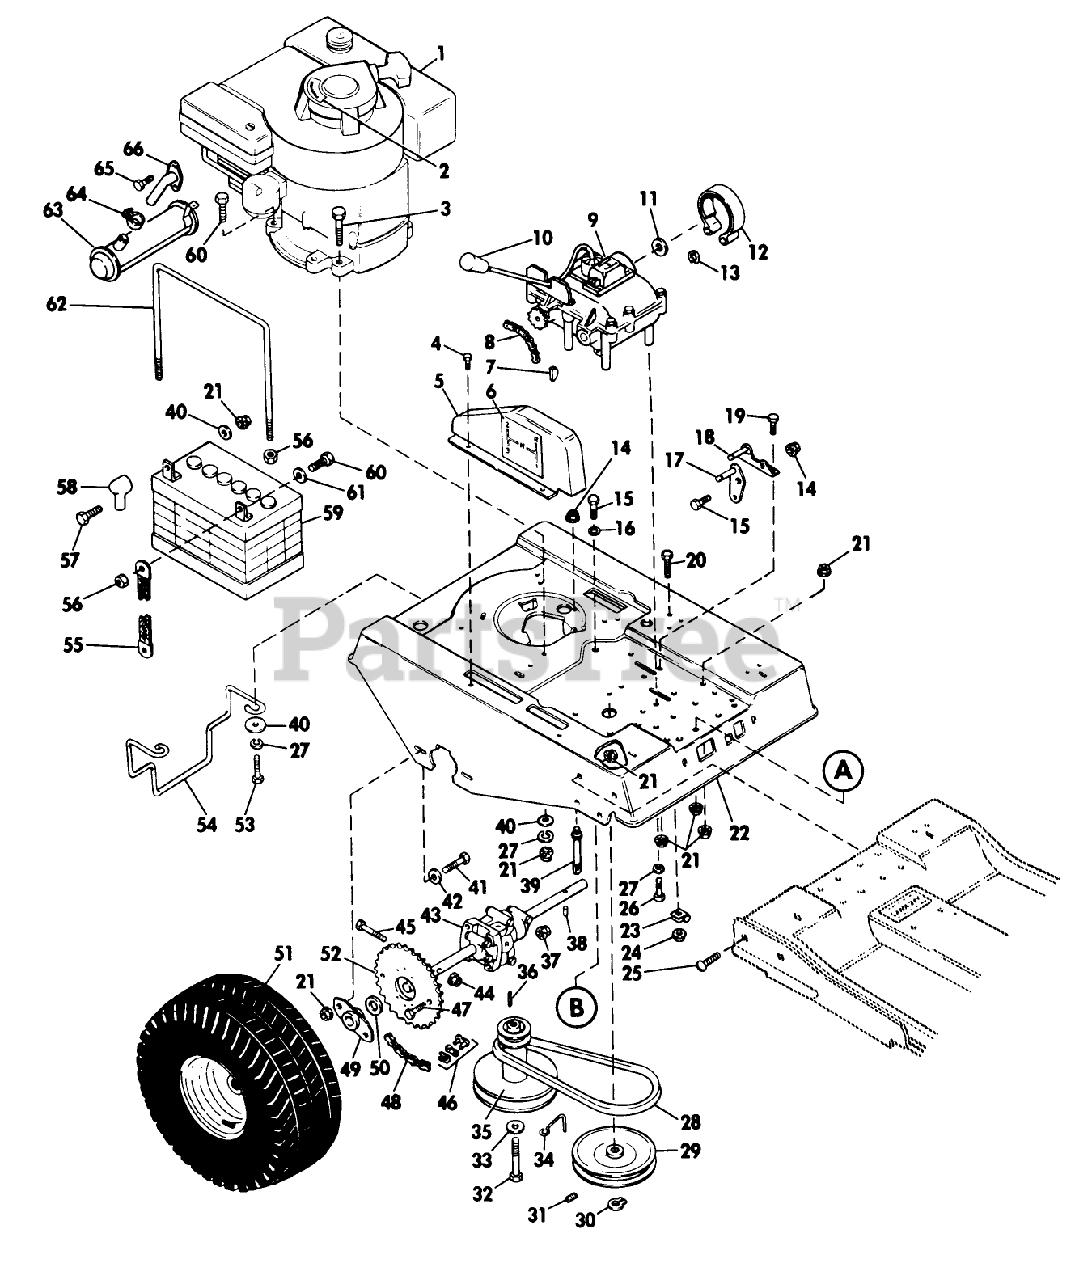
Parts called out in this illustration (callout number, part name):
1	Engine Model 190707 8 H.P. Electric Start
1	Engine Model 191707 8 H.P. Electric Start Synchro
1	Engine Model 190702 8 H.P. Manual Start
2	Decal Start Instructions
5	Chain Guard
6	Decal Shift Pattern
8	Chain-Drive
9	Transmission
10	Knob-Transmission
11	Washer-Thrust
12	Brake Band Assembly
13	Ring-Grip
15	Screw
16	Washer
17	Pivot Assembly
18	Bracket Assembly
21	NUT
22	Frame-Engine Mounting
23	Clamp-Wire Harness
25	Bolt
28	V-Belt
29	Pulley Assembly
32	Screw
33	Washer
35	Engine Sheave Assembly (36" Models)
35	Engine Sheave Assembly
36	Key
37	Nut
38	Roll Pin
39	Eyebolt
43	Differential Assembly
44	LOCKNUT
46	Link-Chain Drive
47	Screw
48	Chain-Drive
49	Bracket Assembly-Rear Axle
50	Washer
51	Wheel and Tire Assembly Rear
52	Sprocket Assembly (45 Tooth)
53	Screw
54	Retainer-Blade Belt (36" Models)
54	Retainer-Blade Belt
55	Cable-Ground
58	Cover-Terminal
59	Battery
60	Screw
62	Battery Hold Down
63	Muffler
64	Clamp-Muffler
66	Exhaust Pipe
